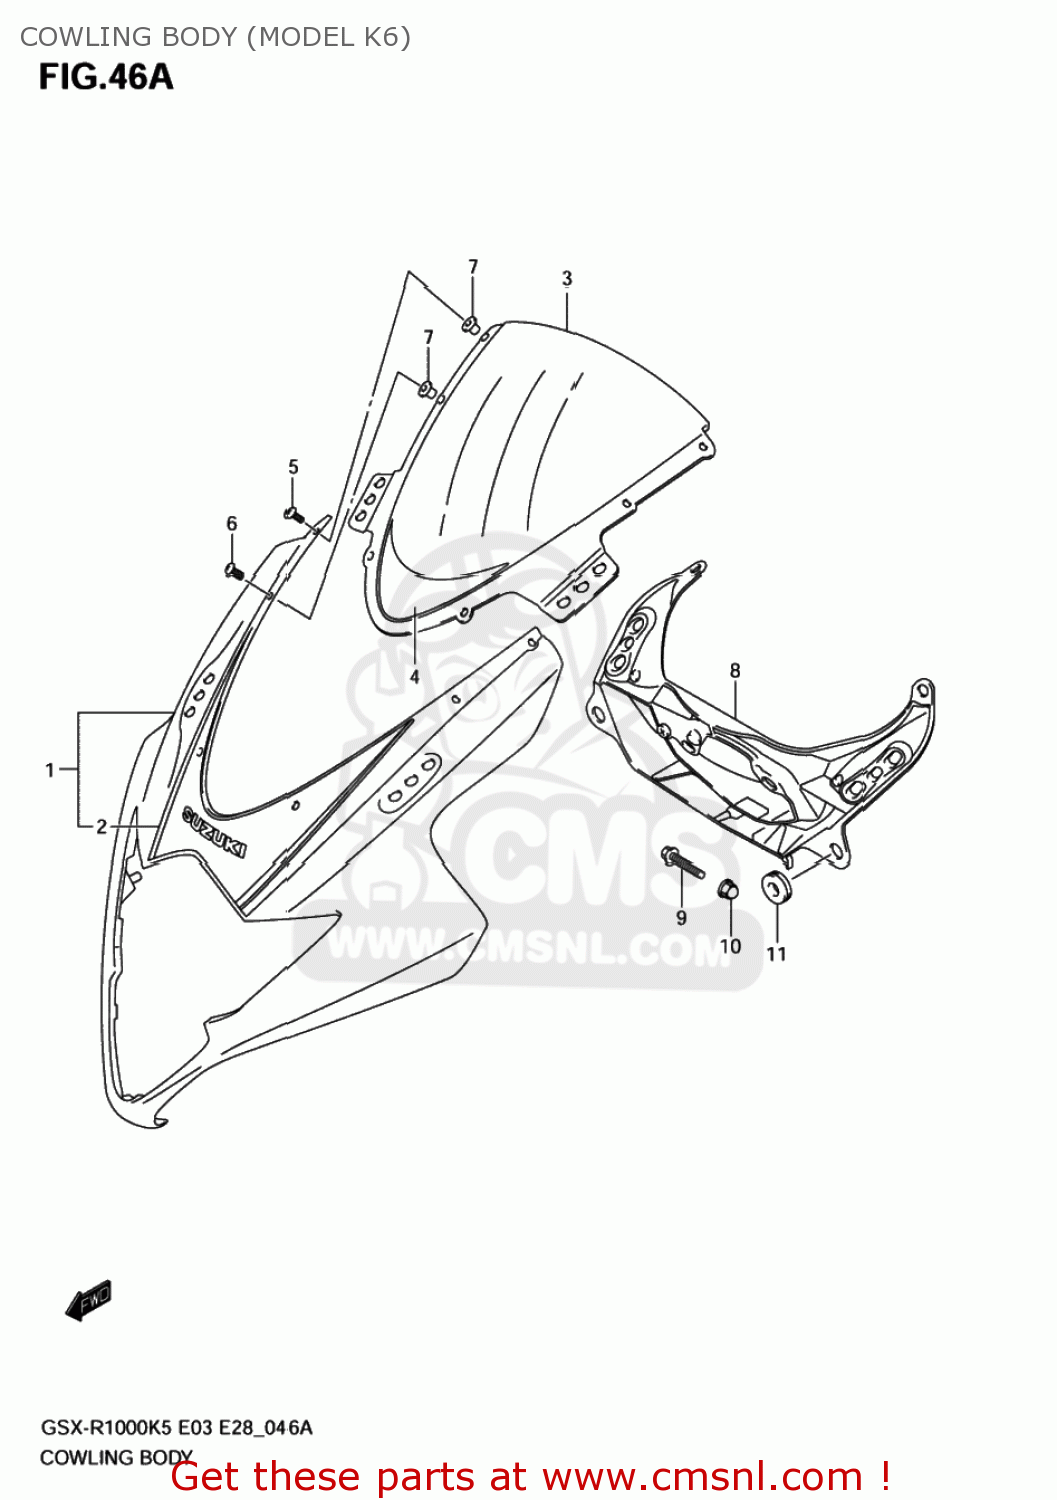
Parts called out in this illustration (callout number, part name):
1	BODY,COWLING
2	TAPE,BODY COWL FR
3	WINDSCREEN
4	TAPE,SCREEN
5	SCREW(5X15)
6	SCREW(5X18)
7	NUT
8	BRACE,COWLING
9	BOLT
10	NUT
11	CUSHION
